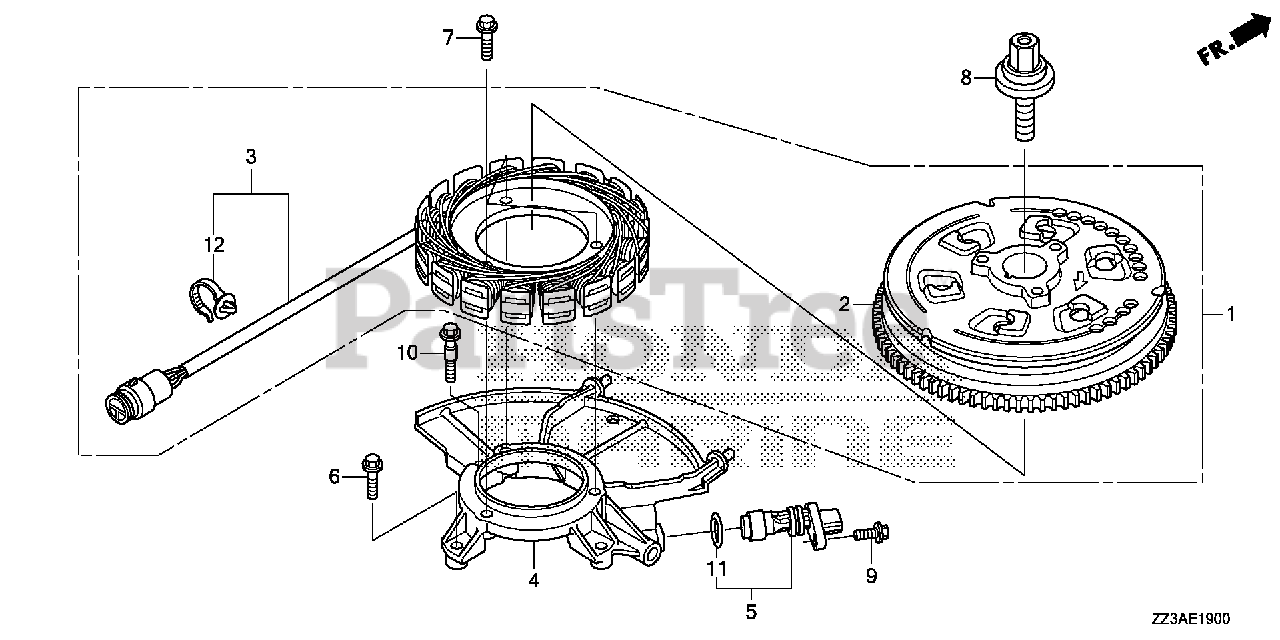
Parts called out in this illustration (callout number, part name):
1	ALTERNATOR ASSY.
4	BRACKET, ALTERNATOR
5	SENSOR ASSY., CRANK
6	BOLT, FLANGE (6X25)
7	BOLT, FLANGE (6X28)
8	BOLT-WASHER (16X49)
9	BOLT, FLANGE (6X16)
10	BOLT, SPECIAL (6X31)
11	O-RING (15X1.9)
12	CLIP, HARNESS BAND (96.9MM) (NATURAL)
